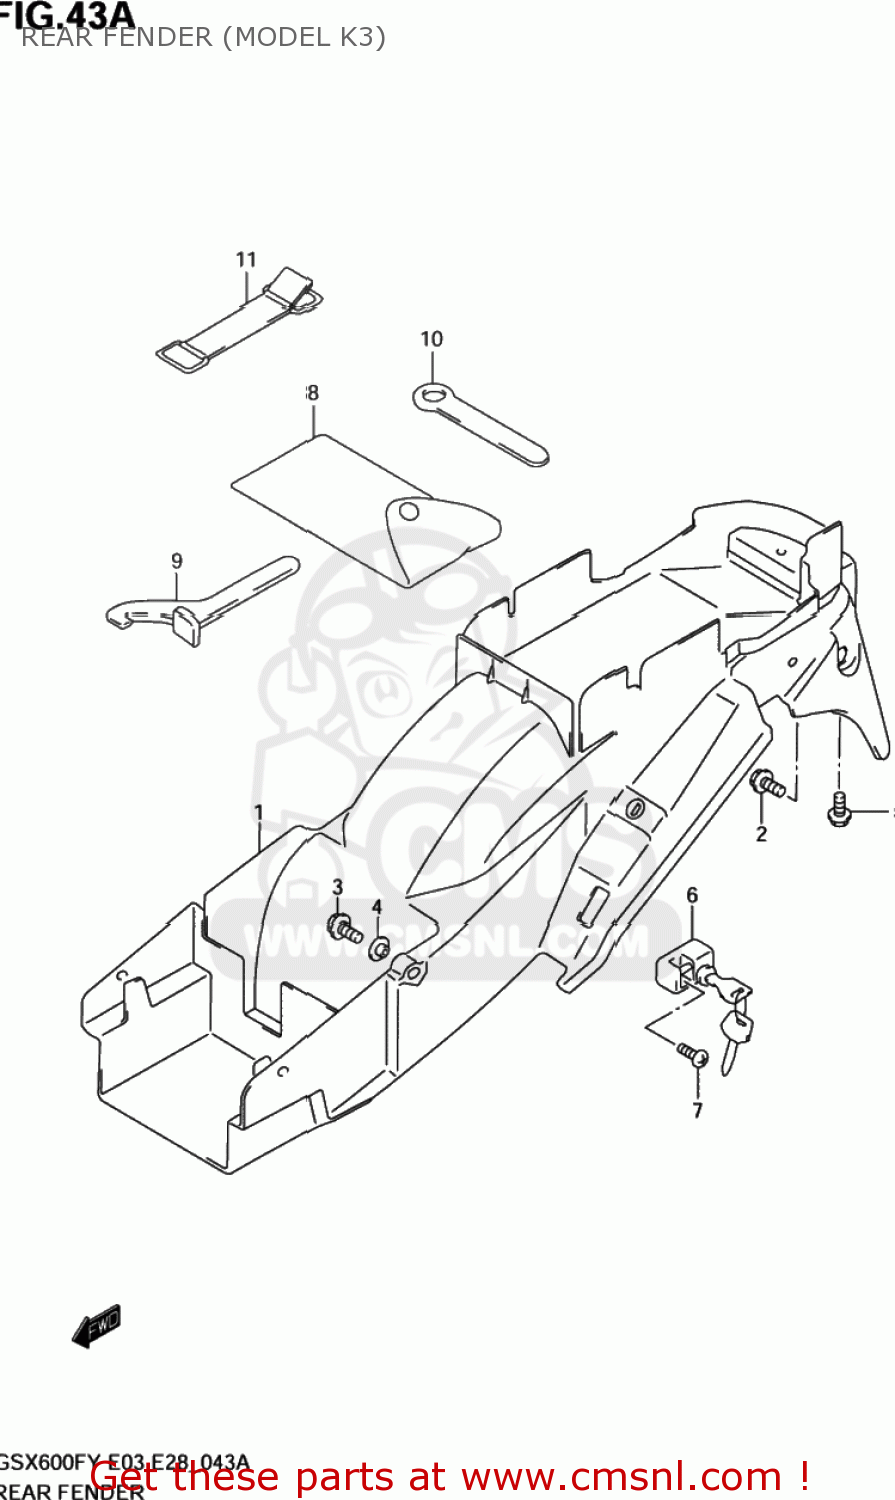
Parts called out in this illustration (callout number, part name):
1	FENDER,RR
2	BOLT(6X16)
3	BOLT
4	WASHER
5	BOLT(6X16)
6	LOCK SET,HELMET
7	SCREW(6X14)
8	TOOL ASSY
9	CLAMP
10	SPANNER,HEXAGON
11	BAND,TOOL
